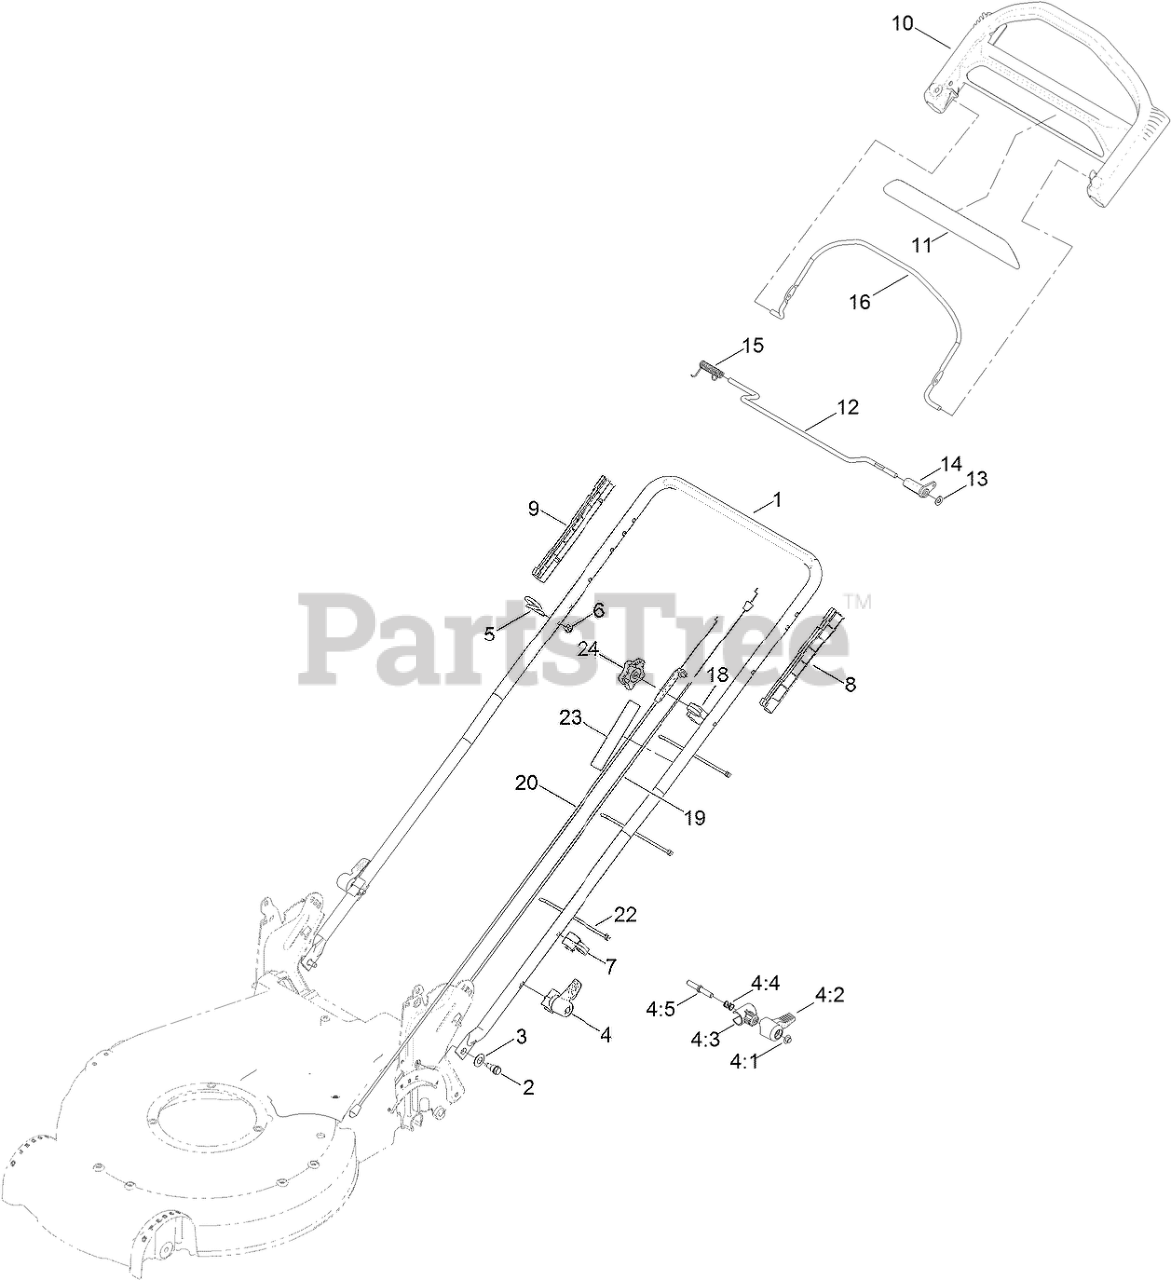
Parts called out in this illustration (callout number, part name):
2	BOLT-SHOULDER
3	WASHER-SPRING, CONICAL
4	QUICK RELEASE ASM
4:1	NUT-PUSH
4:2	LEVER
4:3	ANCHOR-SPRING
4:4	SPRING-COMPRESSION
4:5	ROD-RELEASE
5	GUIDE-ROPE
6	NUT-LOCK, NI
7	GUIDE-CABLE
8	GUIDE-LH
9	GUIDE-RH
10	HANDLE-CONTROL
12	BAR-CONTROL, TRACTION
13	WASHER-PLAIN
14	LEVER-TRACTION
15	Spring-Torsion
16	Bail-Brake
18	ANCHOR-CABLE
19	CABLE-TRACTION
20	CABLE-BRAKE
22	TIE-CABLE
23	DECAL-TRACTION, ADJUST
24	KNOB-HANDLE, LOCKING
